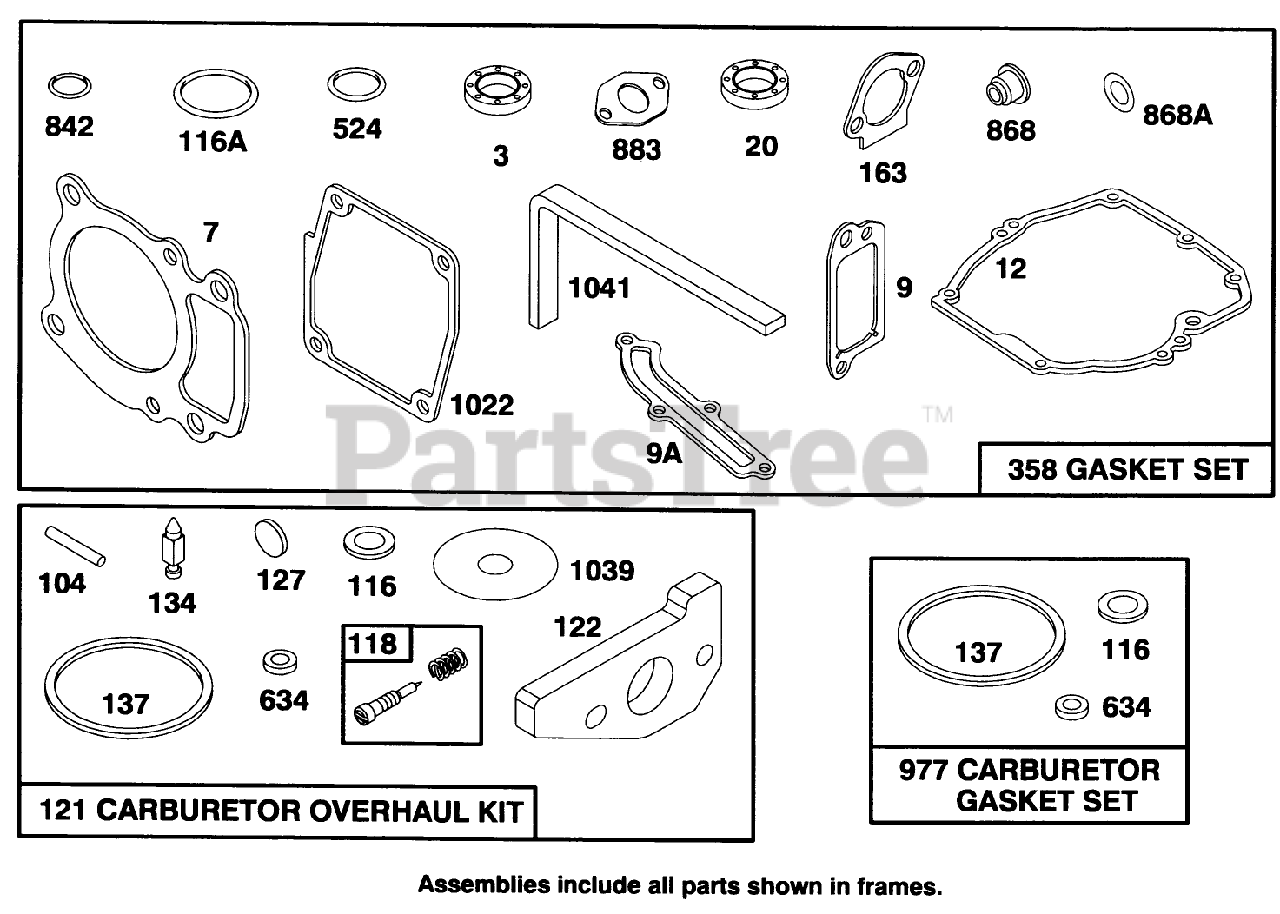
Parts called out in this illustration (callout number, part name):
7	CYLINDER HEAD GASKET
12	ENGINE BASE GASKET
20	SEAL-OIL
116	SEALING GASKET
116A	O RING SEAL
118	VALVE KIT - NEEDLE
121	CARBURATOR OVERHAUL KIT
122	ADAPTER ASSEMBLY
134	VALVE-FLOAT
137	FLOAT BOWL GASKET
163	AIR CLEANER GASKET
358	GASKET SET
524	O-RING
842	O-RING
977	CARBURATOR GASKET SET
1022	ROCKER COVER GASKET
1039	FLOAT LIMITER
